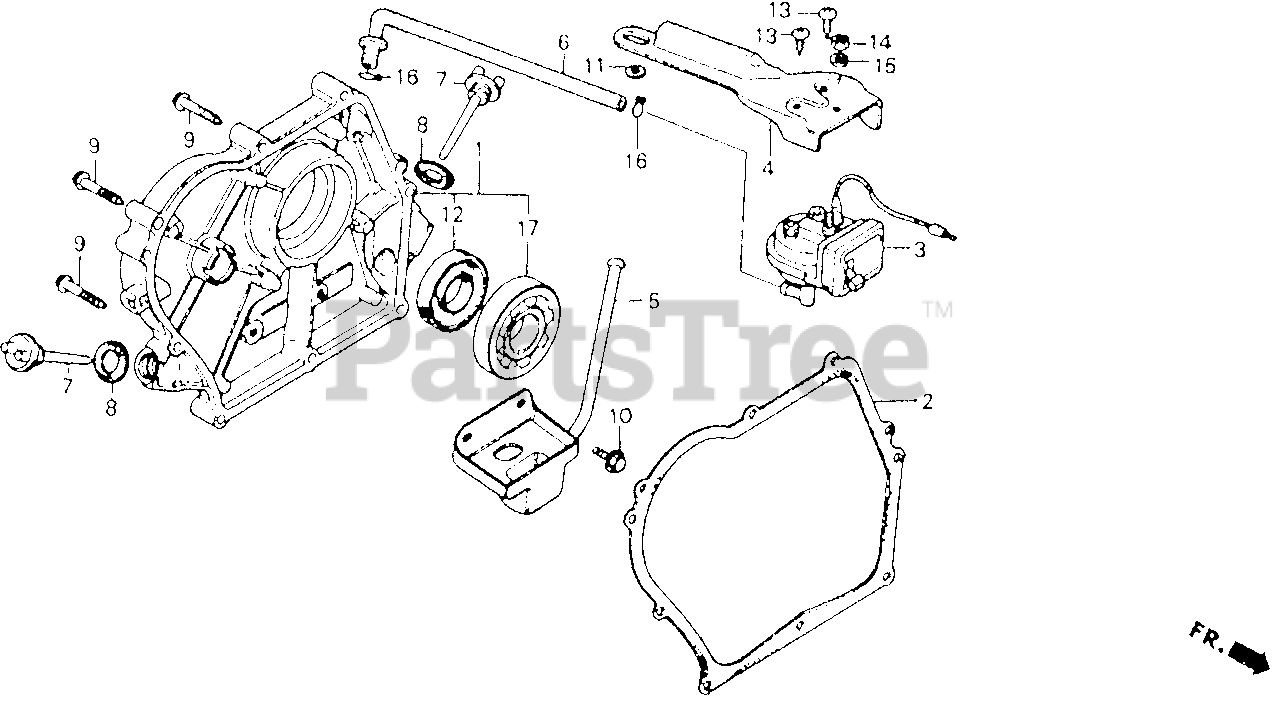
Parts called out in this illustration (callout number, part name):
1	COVER ASSY., CRANKCASE (QZ-TYPE)
2	GASKET, COVER
3	SWITCH ASSY., UNIT
4	BRACKET, UNIT SWITCH
5	CUP, OIL
6	TUBE, OIL ALERT
7	CAP, OIL
8	GASKET, OIL FILLER CAP
9	BOLT, FLANGE (6X32)
10	BOLT, FLANGE (6X16)
11	WASHER (18MM)
12	OIL SEAL (25X41X6)
13	SCREW, TAPPING (5X10)
14	NUT, HEX. (5MM)
15	WASHER, SPRING (5MM)
16	CLIP, TUBE (C11)
17	BEARING, RADIAL BALL (6205)
